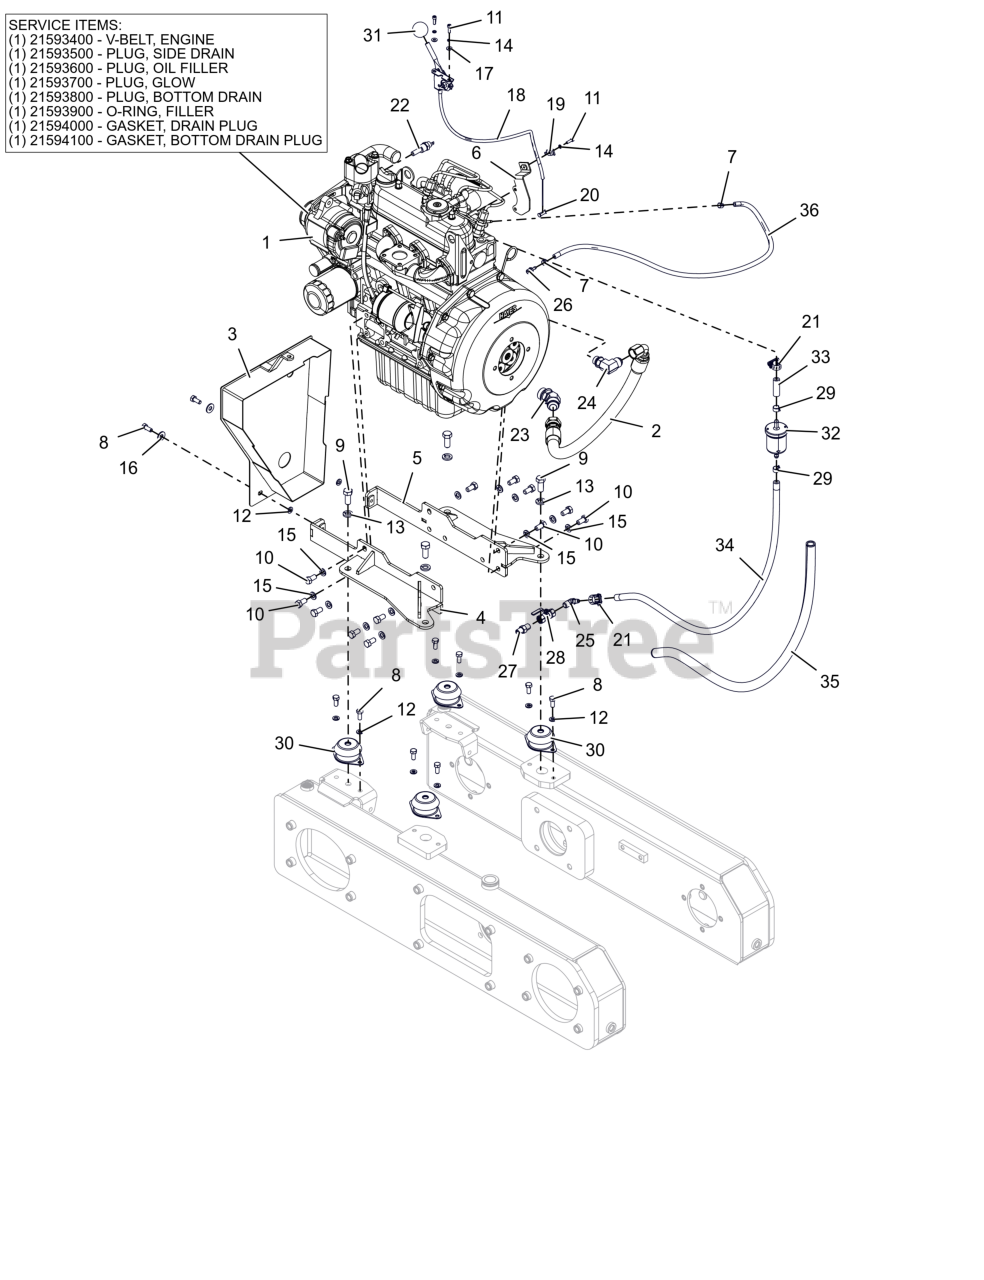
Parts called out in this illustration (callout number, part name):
1	ENGINE, KUBOTA-D1105
1	V-BELT ENGINE
1	PLUG, SIDE DRAIN
1	PLUG, OIL FILLER
1	PLUG, GLOW
1	PLUG, BOTTOM DRAIN
1	O-RING, OIL FILLER
1	GASKET, SIDE DRAIN PLUG
1	GASKET, BOTTOM DRAIN PLUG
2	HOSE, HYD .625" X 45.00" LG
3	COVER, ENGINE (BLACK)
4	MOUNT, ENGINE - RH (BLACK)
5	MOUNT, ENGINE - LH (BLACK)
6	MOUNT, CABLE (BLACK)
7	CLAMP-HOSE, SPRING .188
8	BLT,HEX .31-18X.75 G5 ZCC
9	BLT-BRAKE, M12 X 1.75X30
10	BLT-HEX M10 X 1.25X20 YWZC
11	SCR, SKH 10-32X.625 GR5 ZCC
12	WSHR,LK-REG .312X.078 ZCC
13	WSHR,LK-REG 0.502 X 0.125 ZCC
14	@WSHR-LK #10X.047 REG YWZC
15	WSHR,LK-M10 ZCC
16	WSHR,FLT .375X.875X.083 ZCC
17	WSHR, FLT .219X.500X.049 ZCC
18	CABLE, THROTTLE
19	CLAMP, CABLE
20	SWIVEL, CABLE
21	CLAMP-HOSE WRM .44/.78X.53 F06
22	SWITCH, TEMPERATURE
23	FITTING, HYDRAULIC 6802 12-12
24	FITTING, HYDRAULIC 9059 08-10
25	ELBOW, FUEL - .25NPTX.312 HOSE
26	ADAPTOR, FUEL - .13NPTX.19 HOSE
27	FITTING, HYDRAULIC 5404 04-04
28	VALVE, BALL - .25" NPT
29	CLAMP, HOSE SPRING .313
30	ISOLATOR, ENGINE
31	KNOB, BALL -.375-24
32	FILTER, FUEL
33	GAS LINE, 5/16" ID (PRESSURE)
34	GAS LINE, 5/16" ID (PRESSURE)
35	SPLIT TUBING-22"
36	HOSE, .188 30R7 BULK
